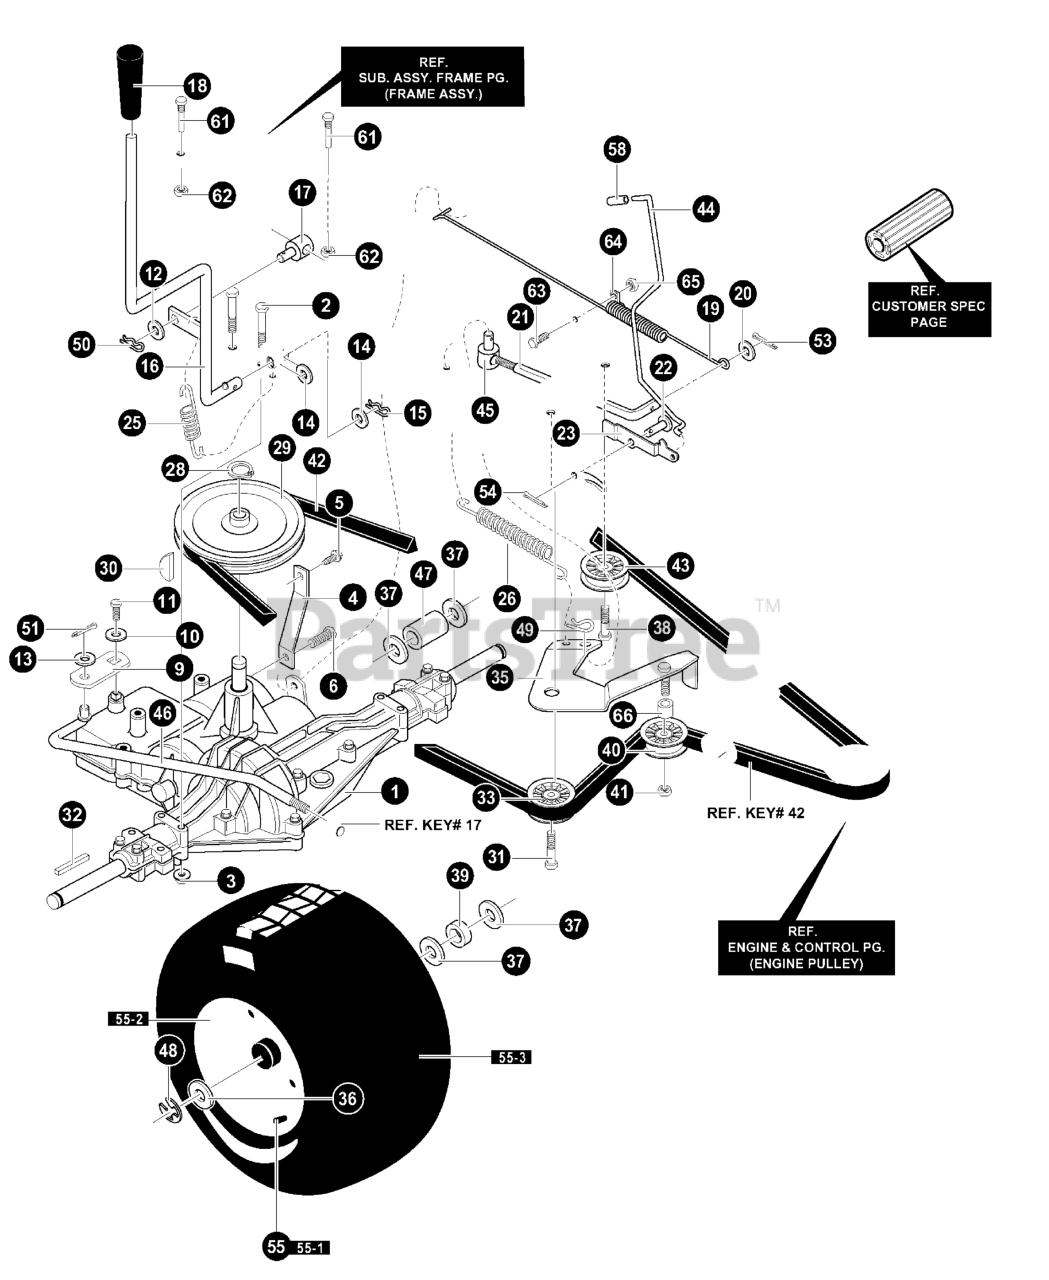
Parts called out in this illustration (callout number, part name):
1	TRANSAXLE MST206-51 **
2	SCREW, 5/16-18 x 2.50
3	NUT, 5/16-18 WDFLLK
4	BRACKET, STABILIZER
5	SCREW, 5/16-18 x .75 HHWATAP
6	SCREW, 5/16-18 x 0.75 WAHHTAP
9	BRACKET, SHIFT
10	WASHER, .750X.250 SP-TRAN
11	SCREW, 1/4-28X.750
12	WASHER, FLAT .391X1.0
13	WASHER, ..406X.8
14	WASHER, FLAT .515X.88
15	HAIR PIN .53DIAX1.62LG
16	SHIFT LEVER
17	NUT, ADJUST 3/8-16
18	GRIP, 1/2"
19	SPRING, BRAKE
20	WASHER, FLAT.328X1.06X.062
21	ROD, CLUTCH
22	PIN, CLEVIS
23	LATCH, PARK BRAKE
25	SPRING, .071X.62X4.
26	SPRING, TENSION
28	RING, RETX .58X.04TR
29	PULLEY, 9.0 OD V4L
30	KEY, HI-PRO 606
31	SCREW, 3/8-16 x 1.25
32	KEY, SQUARE
33	PULLEY, IDLER
35	ASSY, IDLER ARM TRACTION
36	WASHER, FLAT .765 x 1.81 x .059
37	WASHER, FLAT .755ID
38	SCREW, 3/8-16 x 1.25
39	SPACER, .87X1.25
40	PULLEY, IDLER 2.75 DIA
41	NUT, 3/8-16 HWDFLLK
42	BELT, V 4L 114.12
43	PULLEY, IDLER V4L3.00X.710
44	PARK BRAKE CONTROL ROD
45	NUT, 5/16-18X3/8 ADJUSTING
46	ROD, SHIFT LINK
47	SPACER, .87X2.25
48	E-RING .574IDX.050/.75
49	PIN, HAIR .072DIAX1.13LG
50	PIN, HAIR .38DIAX1.64LG
51	PIN, COTTER .094 DIAX.75LG
53	PIN, COTTER .094 DIAX.75LG
54	PIN, COTTER .094 DIAX.75LG
55	TIRE & RIM
55-1	VALVE STEM
55-2	RIM, CARL
55-3	TIRE, 20X8X8
58	CAP, DUMP VALVE ROD
61	SCREW GUIDE
62	NUT, 1/4-20 HEXNYL
63	SCREW, 1/4-20X.50
64	RETAINER .31IDX.62X.0
65	NUT, 1/4-20WDFLWHIZ-LK
66	SPACER, 1/2 TO 17MM
